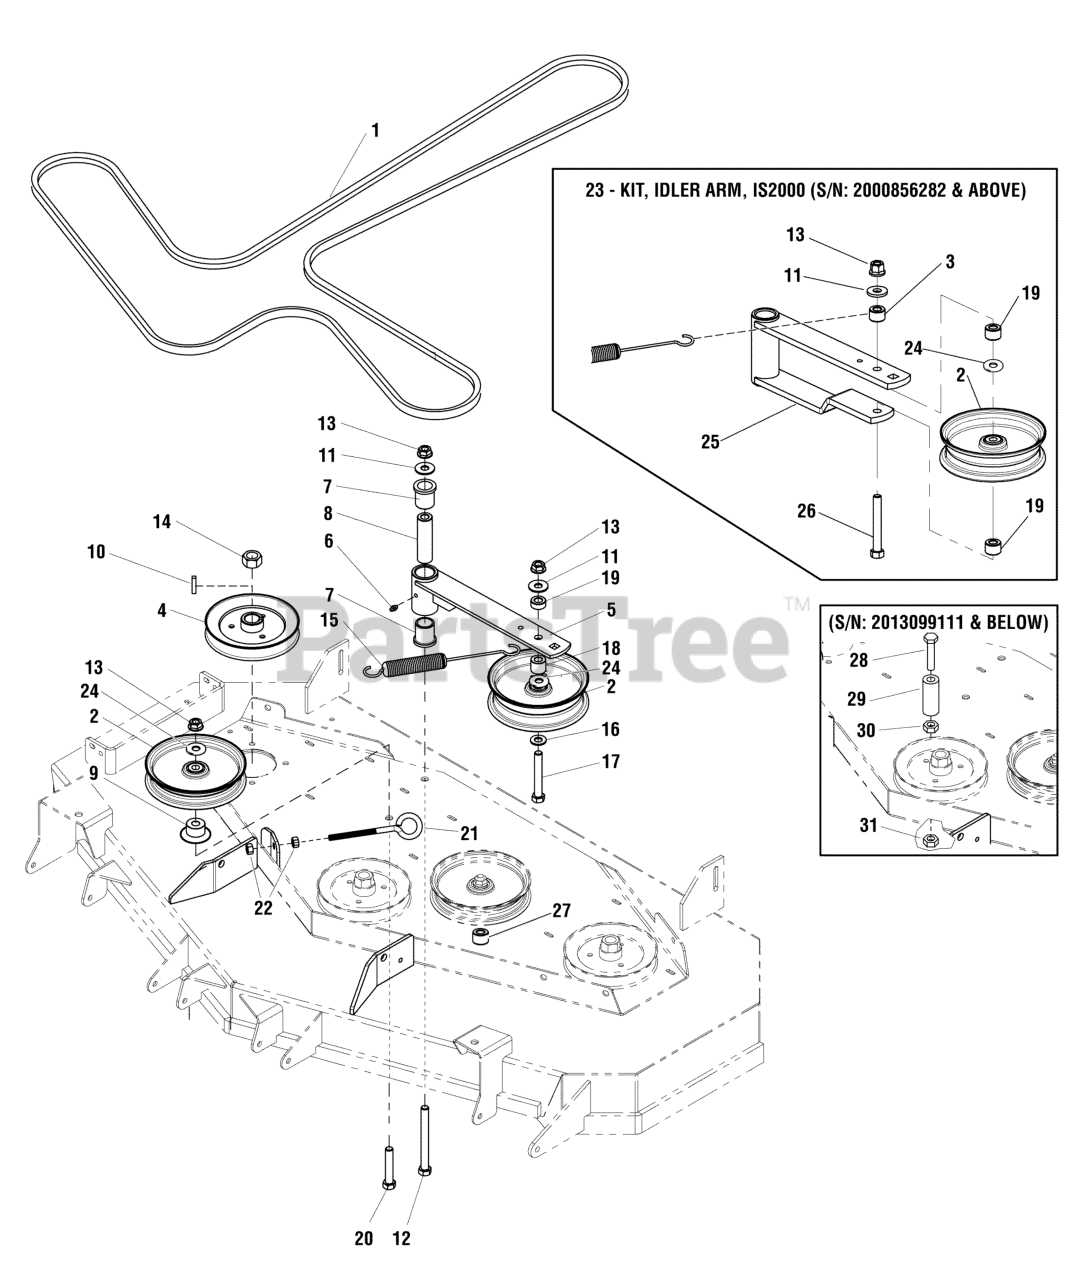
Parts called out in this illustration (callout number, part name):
1	BELT, 5V, 160.60"EL, LRG ARAMID, WRP, RC
3	SPACER, .52 X 1.00 X .22, PM, CZ
4	PULLEY, 6.122 OD X .98 BORE
5	WELD, IDLER ARM - BLK
6	GREASE FITTING, 1/4-28 STR
7	BUSHING, FLANGE
8	SPACER, .52 X 1.00 X 3.50
9	IDLER MOUNT
10	KEY, 1/4" SQ. X 1-1/4
11	WASHER, 1/2" USS
12	BOLT, 1/2-13 X 5" GD5
13	NUT, Hex Flange, Nylock, 1/2-13
14	NUT, 3/4-16 HEX
15	SPRING-EXT, 1.04OD X 10.54LG X .148WR
16	WASHER, 1/2 SAE
17	BOLT, 1/2-13 X 3-1/2, HEX HD, GD5, CZ (SV)
18	SPACER, .52 X 1.00 X .88
19	SPACER, .52 X 1.00 X .44
20	BOLT, 1/2-13 X 2-1/2" GD5 CZ
21	EYE BOLT, 3/8-16 X 4-1/4, 1 EYE
22	NUT, 3/8-16 HEX
23	KIT, IDLER ARM, IS2000
24	SHIELD, PULLEY BEARING
25	WELD, IDLER ARM - BLK
26	BOLT, 1/2-13 X 3-1/4, HEX HD, GD5, CZ (SV)
27	SPACER, .52 X 1.25 X .70
28	BOLT, 1/2-13 X 4" GD5 CZ
29	HOSE, 1/2" PUSH-ON 2.50"
30	NUT, 1/2-13 HEX
31	NUT, Hex Flange, Nylock, 1/2-13
